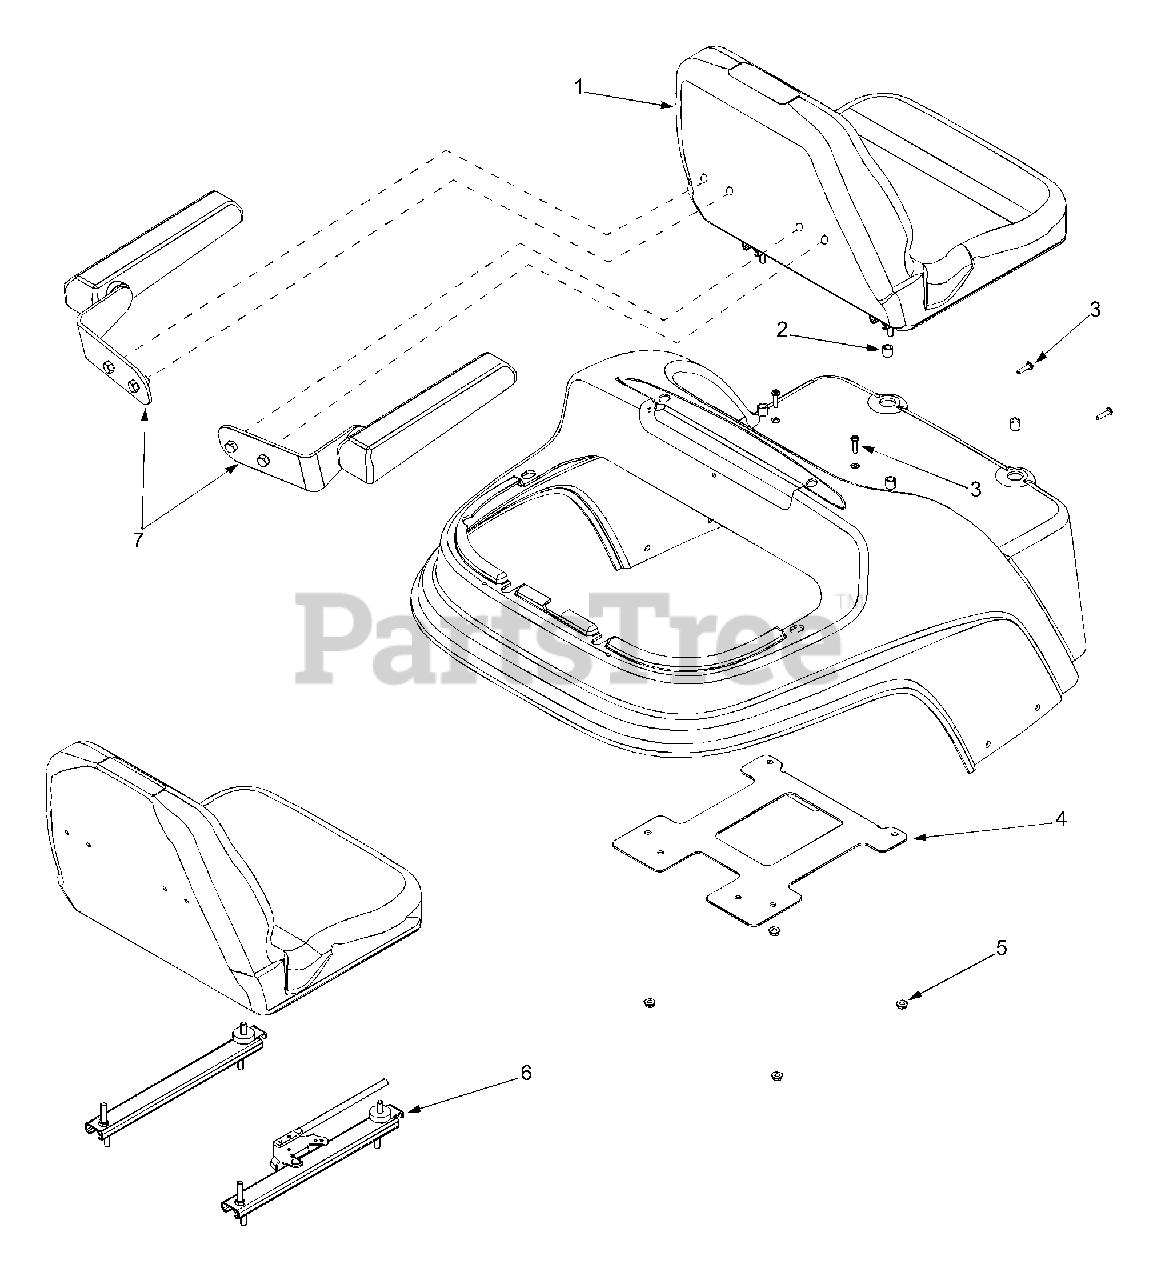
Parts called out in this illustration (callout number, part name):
1	Seat Assembly
2	Spacer .385 x .600 x .570
3	Machine Screw 1/4-20 x .625
4	Seat Plate
5	Flange Lock Nut 5/16-18
6	Seat Track Assembly
7	Arm Rest Set
